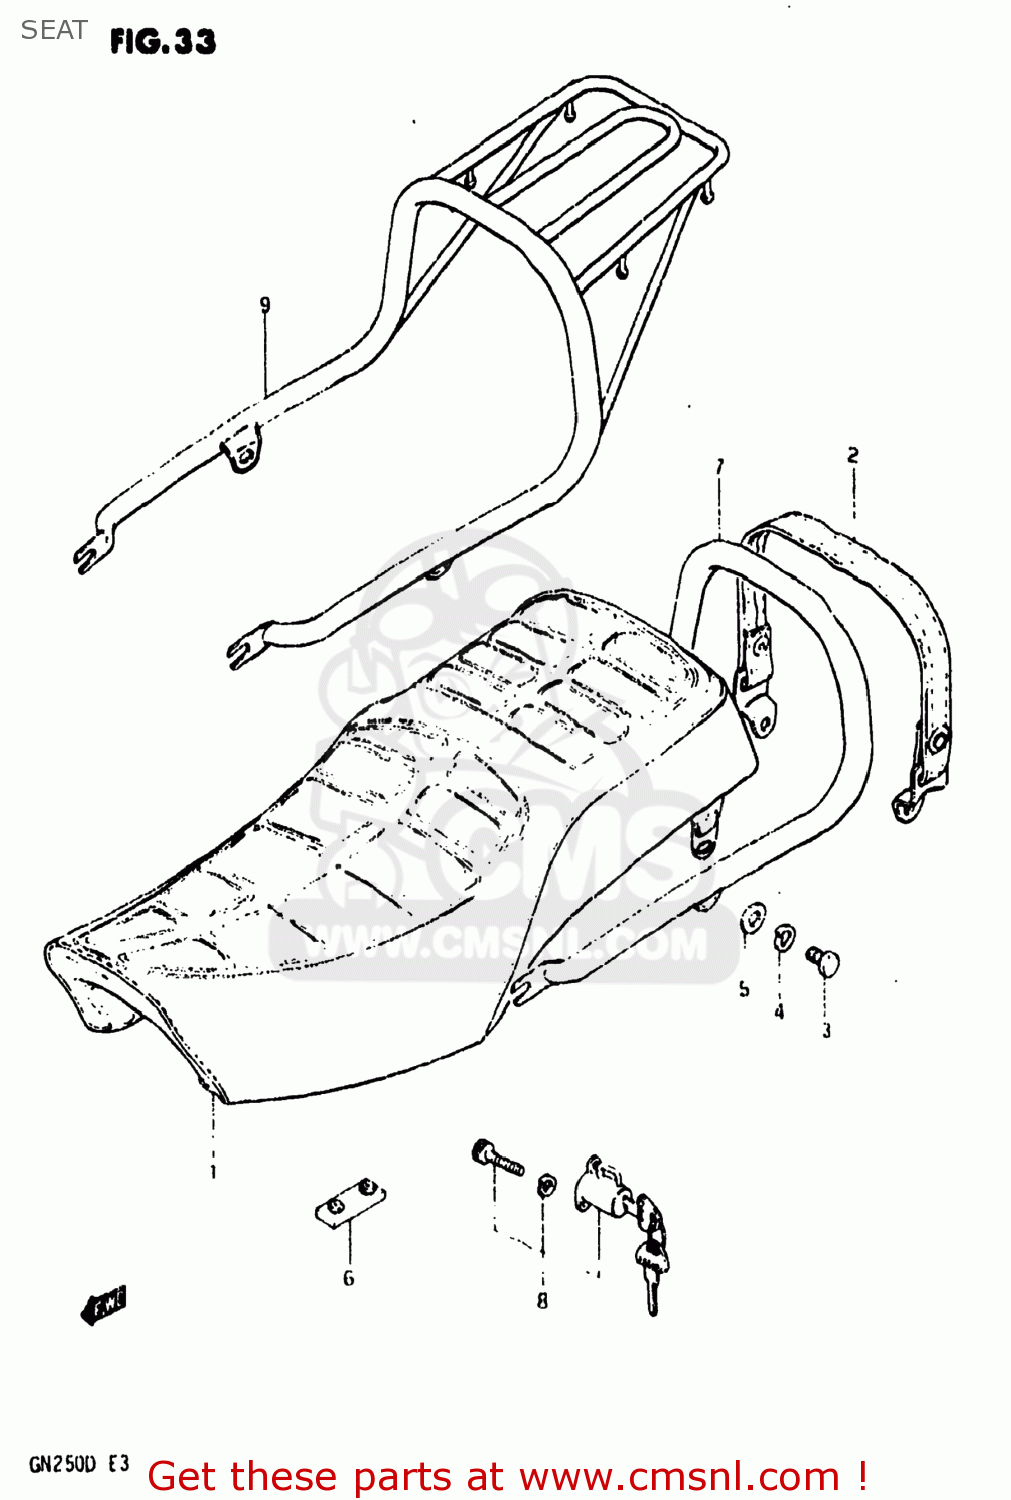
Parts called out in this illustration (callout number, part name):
1	SEAT ASSEMBLY
2	BAND,SEAT
3	BOLT
4	LOCK WASHER
5	WASHER
6	CUSHION
7	HANDLE,PILLION RIDER
8	LOCK SET,HELMET
9	CARRIER
